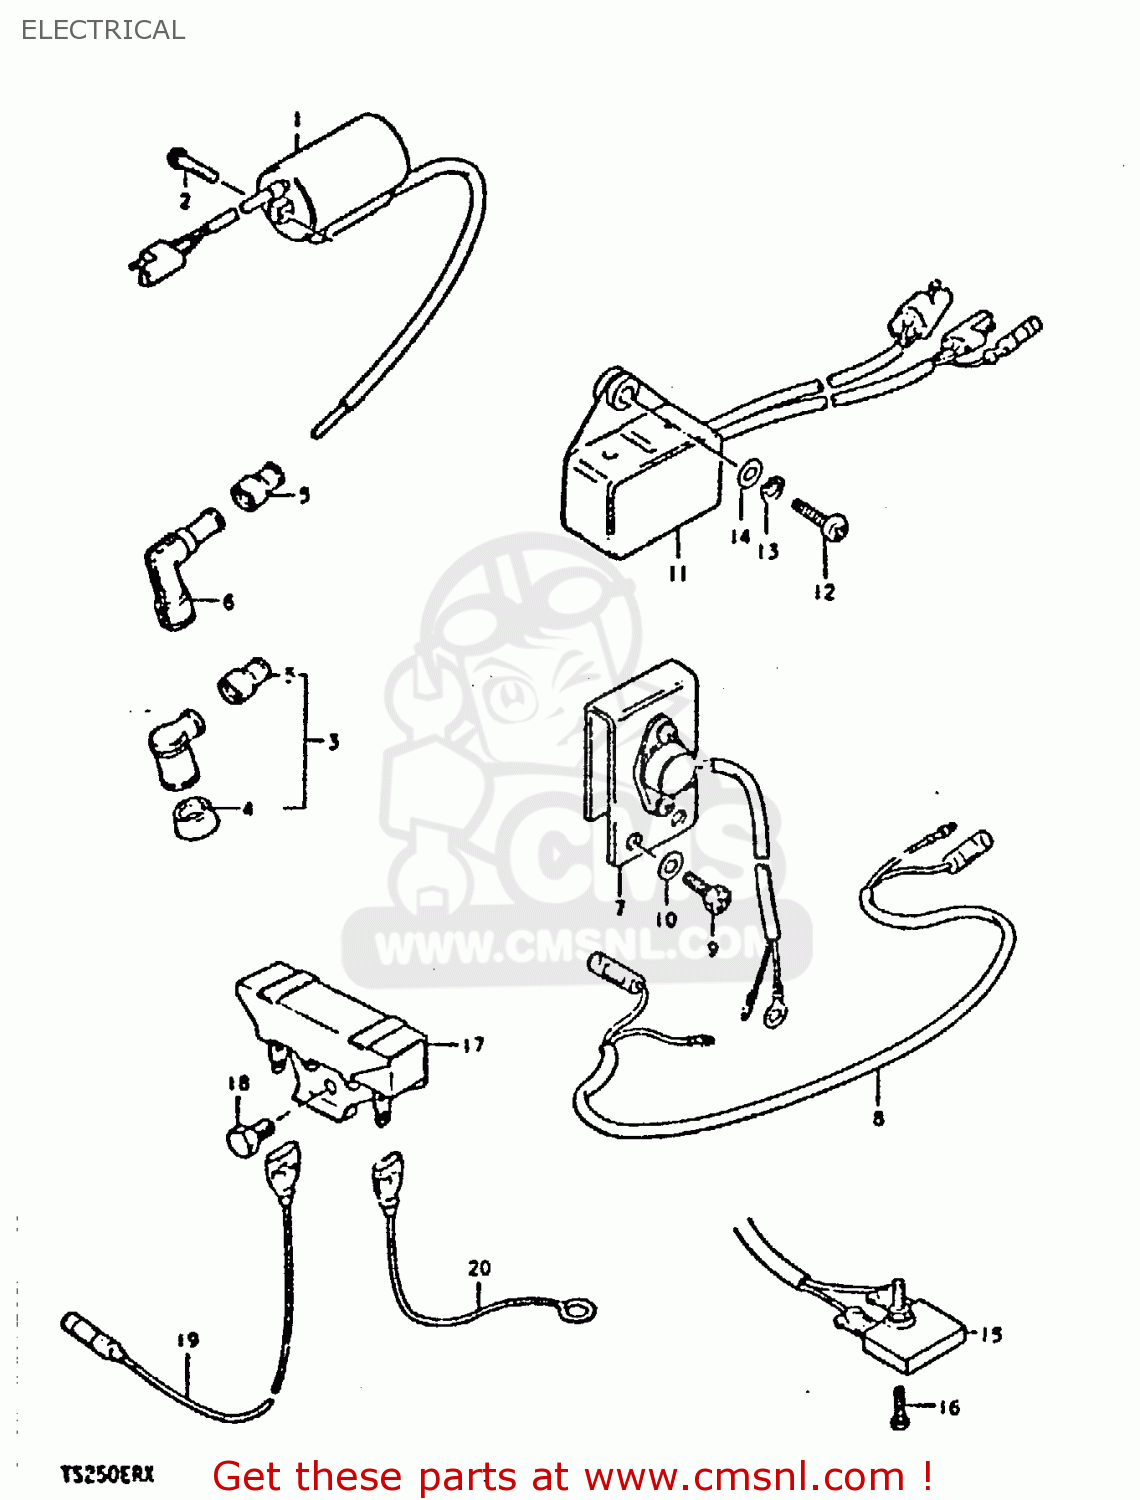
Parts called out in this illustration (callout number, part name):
1	COIL ASSY,IGNITION
2	SCREW 5X20
5	SEAL,SPARK PLU
6	CAP,SPARK PLUG
7	REGULATOR ASSEMBLY
9	SCREW(5X12)
10	WASHER
11	CDI UNIT
12	SCREW
13	LOCK WASHER
14	WASHER
15	RECTIFIER ASSEMBLY
16	SCREW
